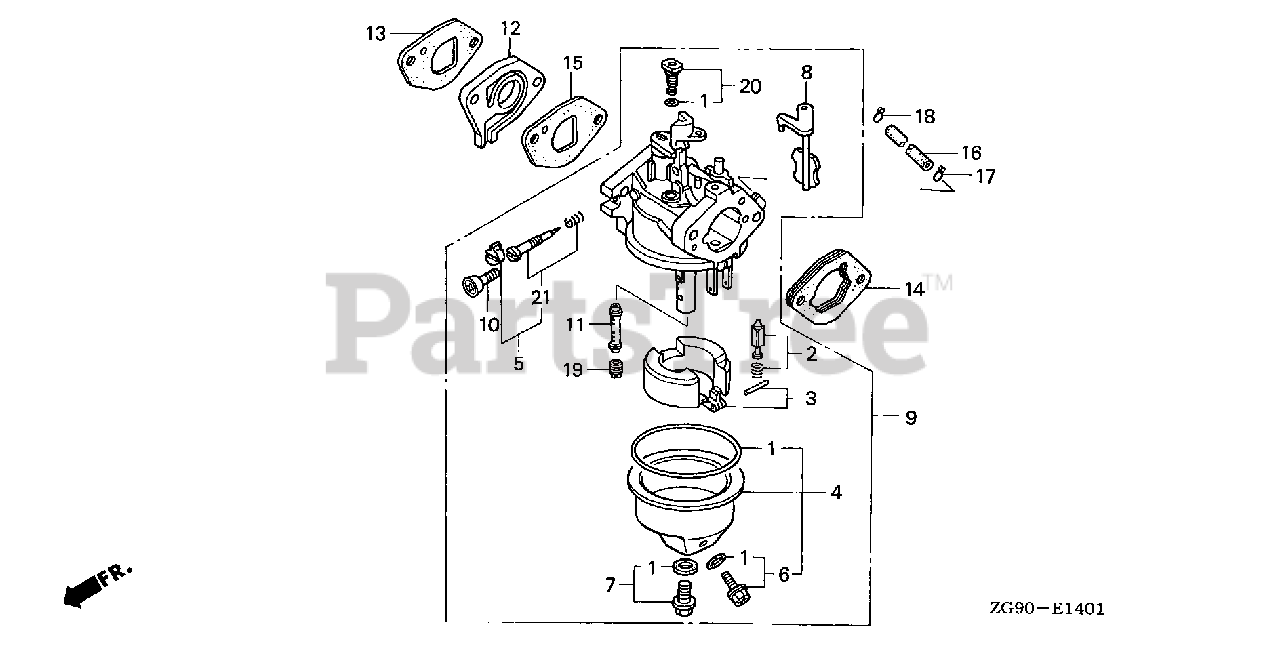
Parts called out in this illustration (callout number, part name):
1	GASKET SET (CARBURETOR NO.)
2	VALVE SET, FLOAT (CARBURETOR NO.)
3	FLOAT SET (CARBURETOR NO.)
4	CHAMBER SET, FLOAT (CARBURETOR NO.)
5	SCREW SET (CARBURETOR NO.)
6	SCREW SET, DRAIN (CARBURETOR NO.)
7	SCREW SET (CARBURETOR NO.)
7	SCREW SET
8	CHOKE SET (CARBURETOR NO.)
9	CARBURETOR ASSY. (BE52B D)
10	SCREW, THROTTLE STOP (CARBURETOR NO.)
11	NOZZLE, MAIN (CARBURETOR NO.)
12	INSULATOR, CARBURETOR
13	GASKET, CARBURETOR
14	SPACER, CARBURETOR
15	GASKET, CARBURETOR
16	TUBE, FUEL VALVE (170MM)
17	CLIP, TUBE (B8)
18	CLIP, TUBE (B10)
19	JET, MAIN (#50) Use from Engine SN BE52B B.
19	JET, MAIN (#52) Use from Engine SN BE52B B.
19	JET, MAIN (#55) (CARBURETOR NO.)
20	JET SET, PILOT (#35) (CARBURETOR NO.)
